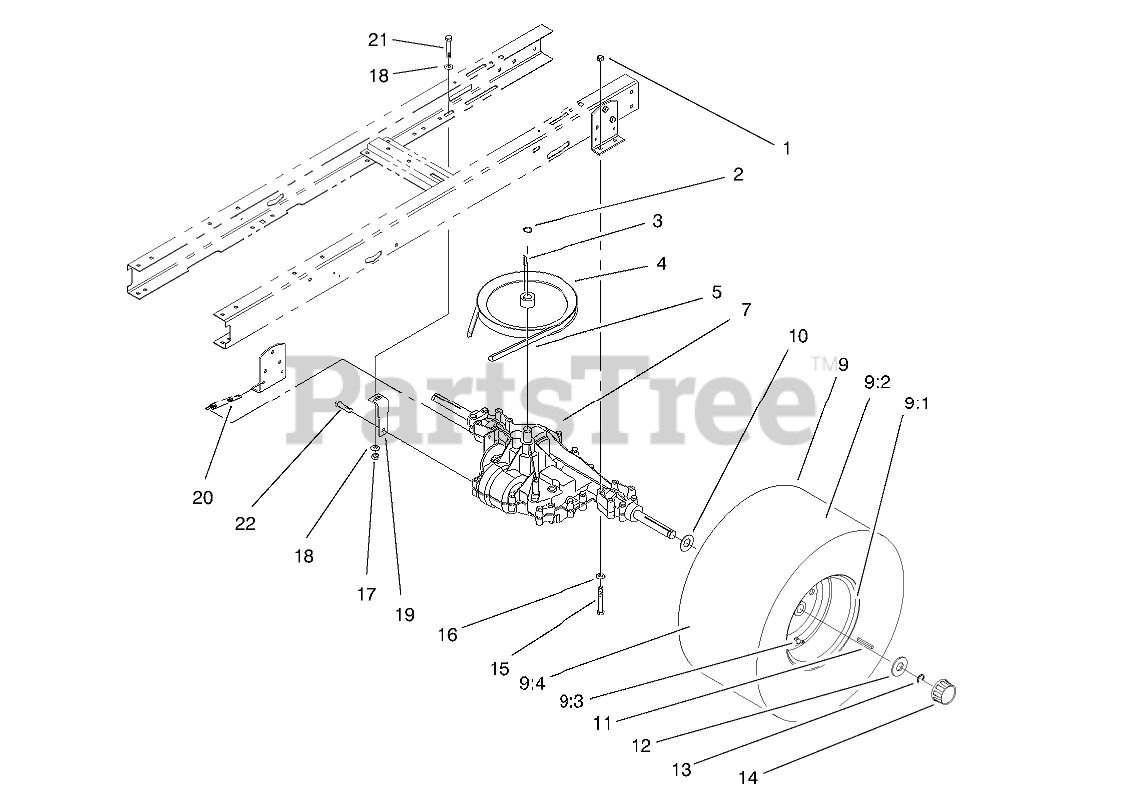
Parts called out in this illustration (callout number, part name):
1	NUT-LOCK, NI
2	RING-SNAP, EXTERNAL
3	KEY-WOODRUFF
4	PULLEY-TRANSMISSION
5	V-BELT
7	TRANSAXLE ASM
9	Rear Wheel & Tire ASM
9:2	TIRE 18 X 9.50 X 8
9:3	STEM-VALVE
9:4	Tube
10	WASHER-THRUST
11	KEY-SQUARE
12	WASHER-PLAIN
13	E-RING
14	CAP-HUB
15	SCREW-HH
16	WASHER-PLAIN
17	NUT-LOCK, NI
18	WASHER-PLAIN
19	STRAP-TORQUE
20	SPRING-RETURN, BRAKE
21	SCREW-HH
22	SCREW-HWHTF
